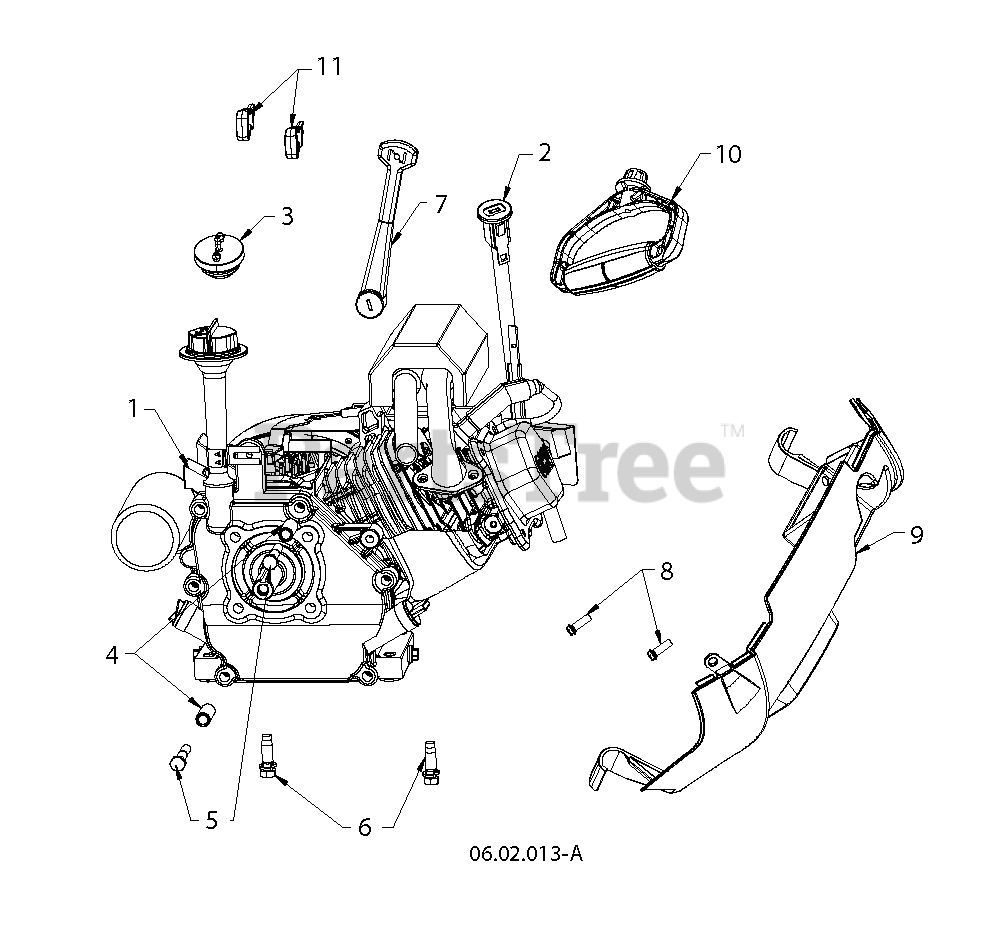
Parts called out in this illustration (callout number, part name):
2	SWITCH.KEY.SST.SNOW
3	RP BULB.PRIMER
4	SPACER.ENGINE
5	SCREW. 5/16-24 X 2.00"HHCS
6	BOLT 3/8-16X1-1/8
7	LEVER.CHOKE
8	SCREW.HX.13X.750
9	COVER.REAR.LOWER.SSST.HUSQ.GRE
10	HANDLE.STARTER.SNOW
11	KIT.SNOW.KEY SET2 GRY.HOP.LOGO
